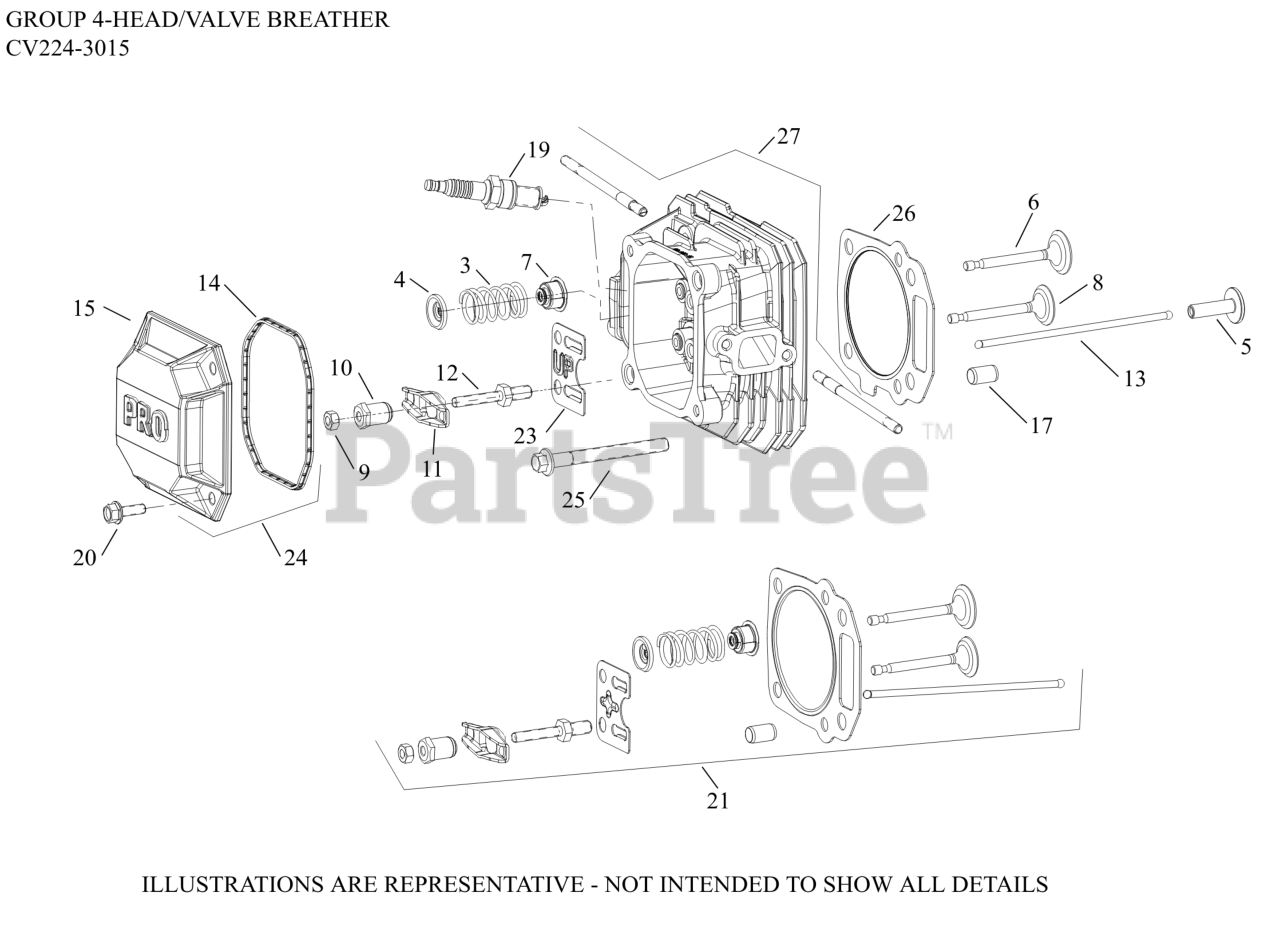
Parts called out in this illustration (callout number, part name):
3	SPRING, VALVE
4	RETAINER, VALVE SPRING
5	LIFTER, VALVE
6	VALVE, INTAKE
7	SEAL, VALVE
8	VALVE, EXHAUST
9	NUT, HEX JAM
10	PIVOT, ROCKER ARM
11	ARM, ROCKER (1.2: 1 RATIO)
12	STUD, ROCKER ARM
13	ROD, PUSH-(#1741108S)
14	SEAL, VALVE COVER
15	COVER, VALVE-USE 14 096 184-S
17	DOWEL, CYLINDER HEAD
19	PLUG, SPARK 12MM RFI
20	SCREW, HEX FLANGE (M6)
21	KIT, VALVE TRAIN
23	PLATE, PUSHROD GUIDE
24	COVER, VALVE ASSEMBLY
25	SCREW, HEX FLANGE (M8)
26	KIT, HEAD GASKET
27	KIT, CYLINDER HEAD-USE 14 818 01-S
